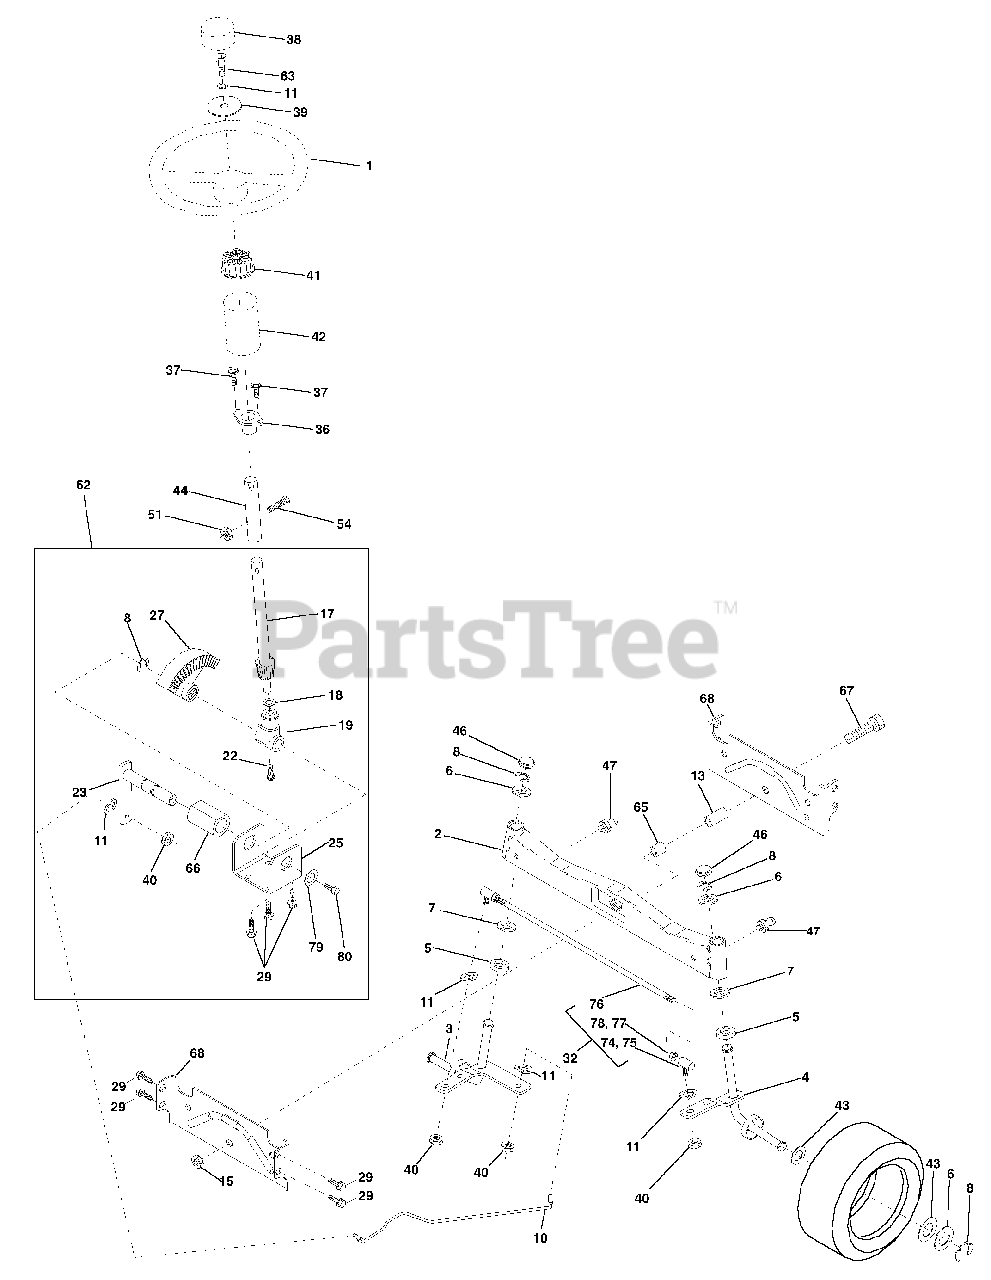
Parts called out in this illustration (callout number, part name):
1	Steering Wheel
2	Axle, Front
3	Spindle, L.H.
4	Spindle, R.H.
5	Bearing, Thrust
6	Washer 25/32 x 1-5/8 x 16 Gauge
7	Washer 27/32 x 1-1/4 x 16 Ga.
10	Link, Drag
11	Washer, Lock 3/8
12	Nut, Hex, Jam, Top Lock 1/2-20 UNF
13	Bearing Axle
15	Locknut, Hex with Washer Insert 5/8-11 UNC
17	Shaft, Steering
19	Shaft, Support
22	Screw Hex Wsh hd Torx
23	Shaft, Pitman
25	Bracket, Steering
27	Gear, Sector
29	Screw, Hex Washer Head, Thdrol. 3/8-16 x 3/4
32	Rod, Tie
36	Bushing Steering
37	Screw TT #10-32 X 5 x 3/8 Flange
38	Insert, Steering Wheel
39	Washer
40	Nut, Lock Center 3/8-24 UNF
41	Adapter, Steering Wheel
42	Boot Steering Dash P/L Mtl
43	Washer, 25/32 x 1-1/4 x 16 Gauge
44	Extension Steering Non-Adjust
46	Spindle, Cap
47	Grease Zerk
51	Nut Lock Hx w/Ins. 5/16-18 Unc
54	Bolt Fin Hex 5/16-18 Unc x 1-1/4
62	Kit Steering Asm Service
63	Bolt Fin Hex 3/8-16 Unc x 1 Gr. 5
65	Spacer Axle
66	Bearing Arm Pittman
67	Bolt Fin Hex 5/8-11 UNC x 2-3/4
68	Brace Axle
74	Joint Asm Ball Rh
75	Joint Asm Ball Lh
76	Rod Tie Ball J Adj
77	Nut Hex Jam 3/8-24 Unf Lh
78	Nut Hex Jam 3/8-24 Unf
79	Washer 13/32 x 1-1/4 x 12 Ga
80	Bolt Hex Nylon 3/8-16 x 3/4
